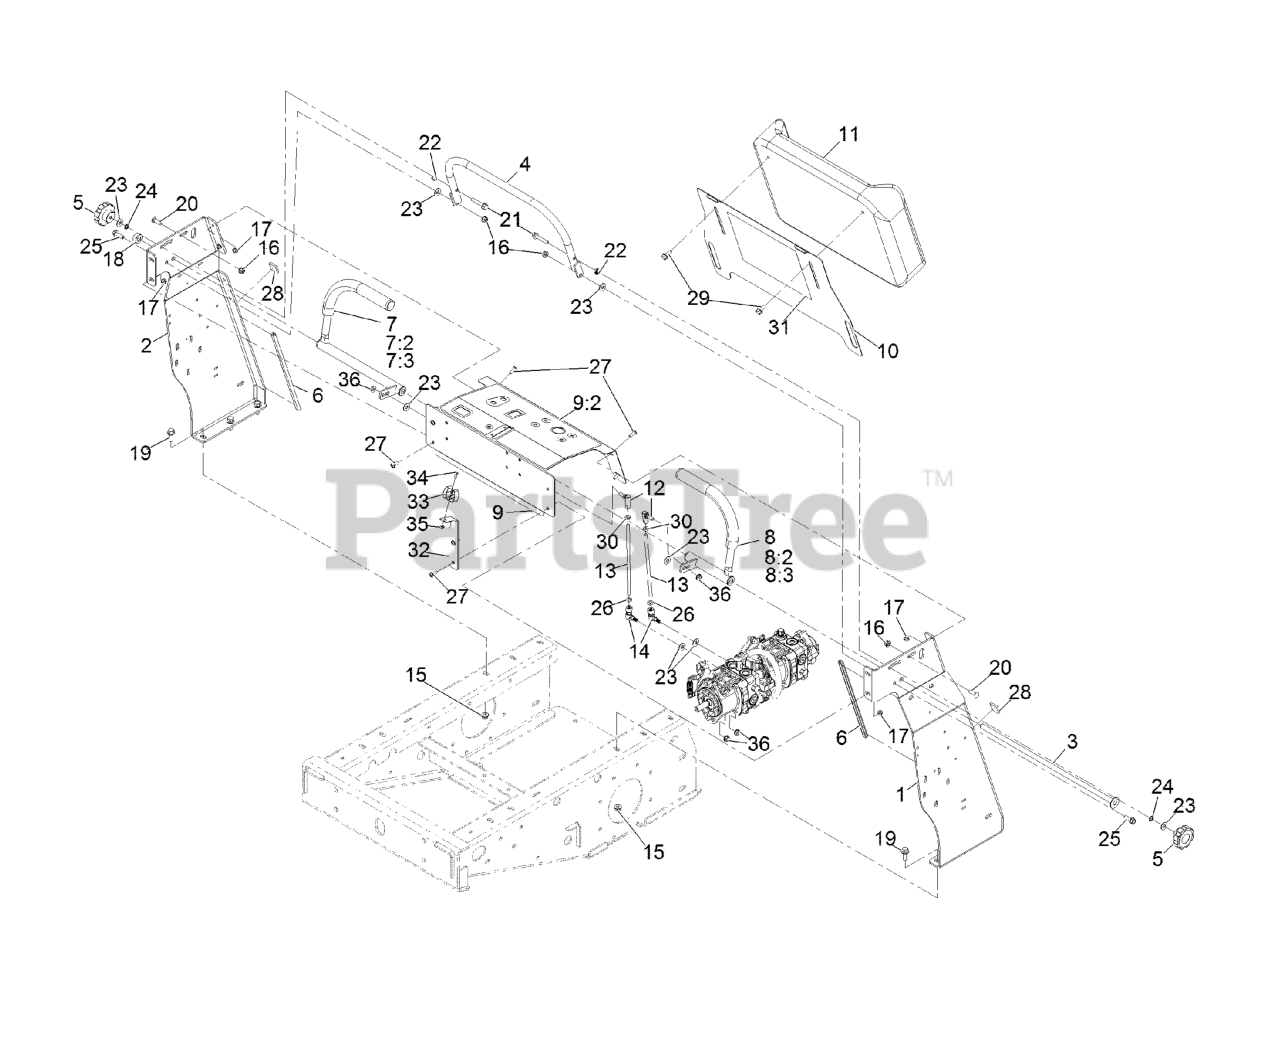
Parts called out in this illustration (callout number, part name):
1	Upright-Tower, Lt
2	Upright-Tower, Rt
3	Rod-Pivot, Joy Stick
4	Bar-Speed
5	KNOB-FLUTED
6	STRIP-TRIM, 12.0"
7	Stick-Joy, Rt
7:2	GRIP-CONTROL, MOTION
7:3	BUSHING-FLANGE
8	Stick-Joy, Lt
8:2	GRIP-CONTROL, MOTION
8:3	BUSHING-FLANGE
9	Panel-Control
9:2	DECAL-CONTROL PANEL
10	PLATE, KNEE PAD
11	Pad-Knee, Z-Spray/Z-Plug
12	Balljoint-SS
13	ROD-CONTROL, MOTION
14	Ball Joint-Quick Disconnect, SS
15	Nut-Hex Flange
16	Nut-Hex Flange
17	Nut-Hex Flange
19	SCREW-HHF
20	Bolt,Carriage,5/16-18X1,ST/ST 18-8
21	Screw-HHF
22	Nut,Hex Flange,5/16-18,Sst, Rie2006
23	FLAT WASHER, 5/16 NOM,ST
24	Washer-Lock
25	SCREW-HHF
26	Nut-Hex
27	Screw-Hsbhf
29	SCREW-HHF
30	Nut-Hex
31	DECAL-SPRAY CHART
32	Mount-Gun
33	Holder-Tool, Clip
34	Screw-HSBH
35	Nut-Hex Flange
36	Nut-HHF
